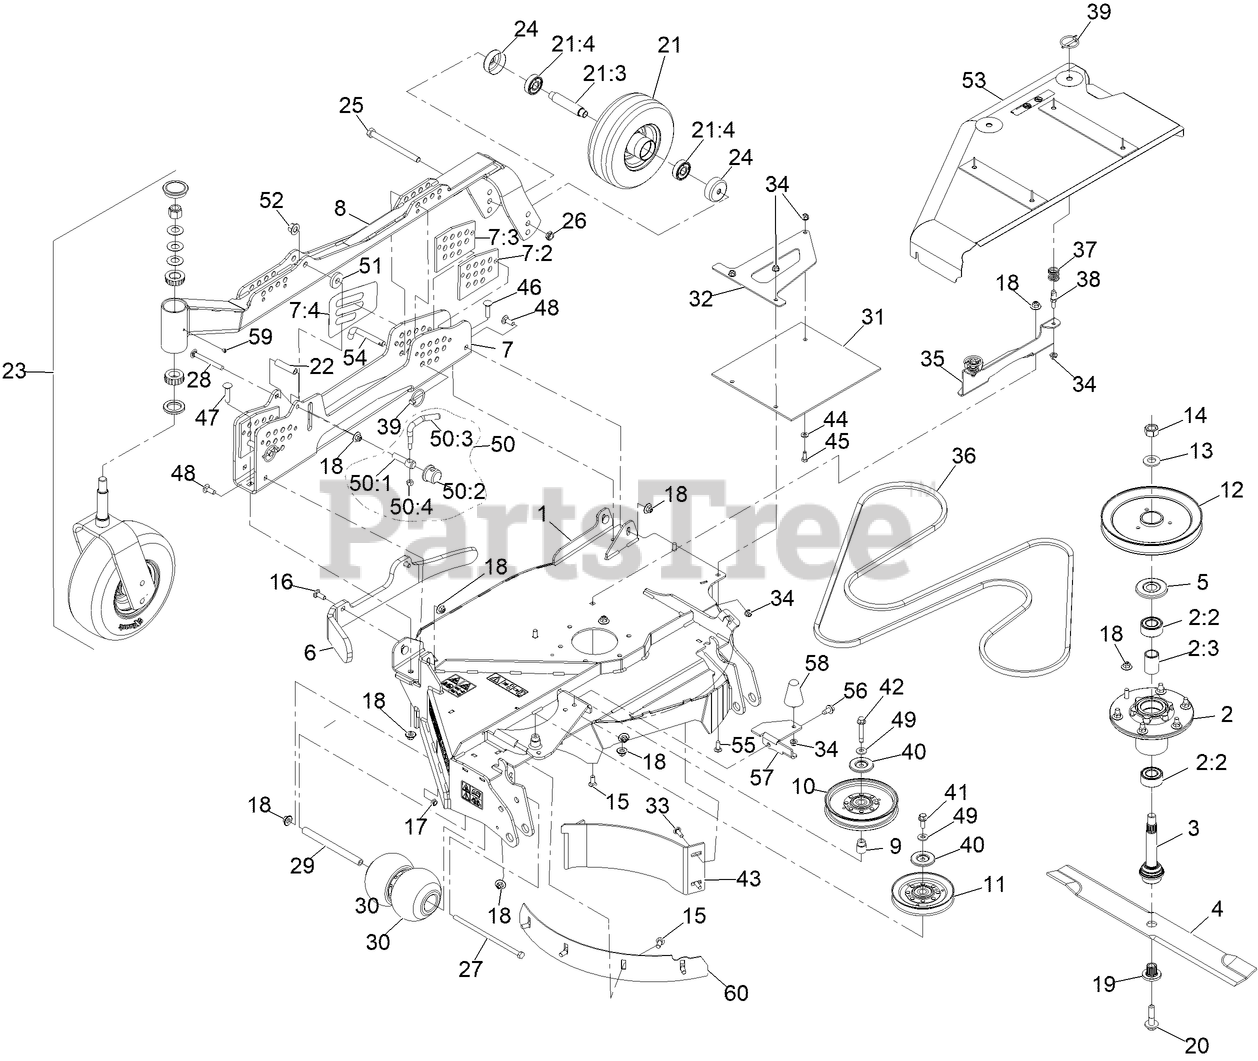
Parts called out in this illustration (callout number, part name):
1	ASM-DECK, RH WING 96
2	ASM-CUTTER HSG
2:2	BEARING-3205 TRASHGUARD
2:3	SPACER-BEARING
3	ASM-SPINDLE AND SEAL
5	GUARD-BEARING, TOP
6	BUMPER-96 RH
7	RH HOC CHANNEL ASM
7:2	PLATE-GUIDE, HOC (LH)
7:3	PLATE-GUIDE, HOC (RH)
7:4	DECAL-HEIGHT OF CUT, RH
8	CALL CUSTOMER SERVICE
9	BUSHING-IDLER
10	IDLER-PULLEY
11	IDLER-V
12	SHEAVE-SINGLE 96RD
14	NUT-HEX
15	BOLT-CARR
16	SCREW-CARR
18	Nut-Nyloc 3/8-16 Flg
19	BUSHING,SPLINED
20	SCREW,SEMS 1/2-20 X 2.19
21	WHEEL AND TIRE ASM
21:3	AXLE-CASTER
21:4	BEARING
24	GUARD, SEAL
25	SCREW-HH
26	NUT-HEX
27	SCREW-HH
28	SCREW-CARR
29	SPACER-WHEEL
30	ROLLER-SCALP, ANTI
31	GUARD-TIRE
32	SUPPORT-FLAP, RH
33	SCREW-CARR
34	NUT-HF, NI
35	BRACKET-SHIELD MOUNT, OUT
38	PIN, SPRING
39	PIN-LYNCH
40	SHIELD-DUST
41	SCREW-HHF 3/8-16 X 1
42	SCREW-HHF
43	BAFFLE-BLOCK, RH WING
44	WASHER-PLAIN
45	SCREW-HH
46	SCREW-CARR
47	SCREW-CARR
48	BOLT-CARR
49	WASHER-BELLEVILLE
50	LEVER ASM
50:1	SCREW-LOCK
50:2	CAP-LOCK
50:4	NUT-LOCK, NI
52	Nut-Lock 1/2-13
53	ASM-Wing Shield RH
54	PIN-HOC
55	BOLT-CARR
56	SCREW-HWH
57	BRACKET-COVER RETAINER
58	BUMPER-RUBBER
60	BAFFLE-DEPTH, RH
